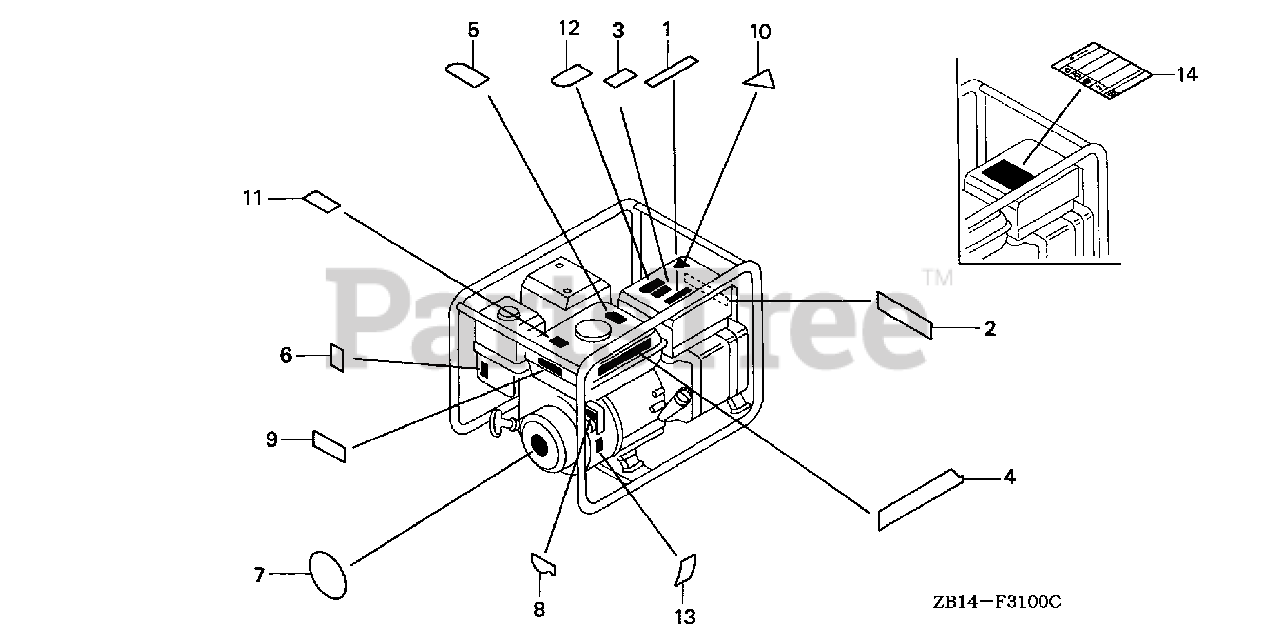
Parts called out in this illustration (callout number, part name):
2	PLATE, CAUTION
3	LABEL, RAIN WARNING (ENGLISH)
4	EMBLEM, FUEL TANK
5	MARK, CAUTION (ENGLISH/FRENCH/SPANISH)
6	MARK, CHOKE
7	MARK, HONDA
8	MARK, OIL ALERT (EXTERNAL)
11	MARK, CAUTION (ENGLISH/FRENCH/SPANISH)
12	LABEL, CONNECT WARNING (ENGLISH)
13	MARK, OIL CAUTION
